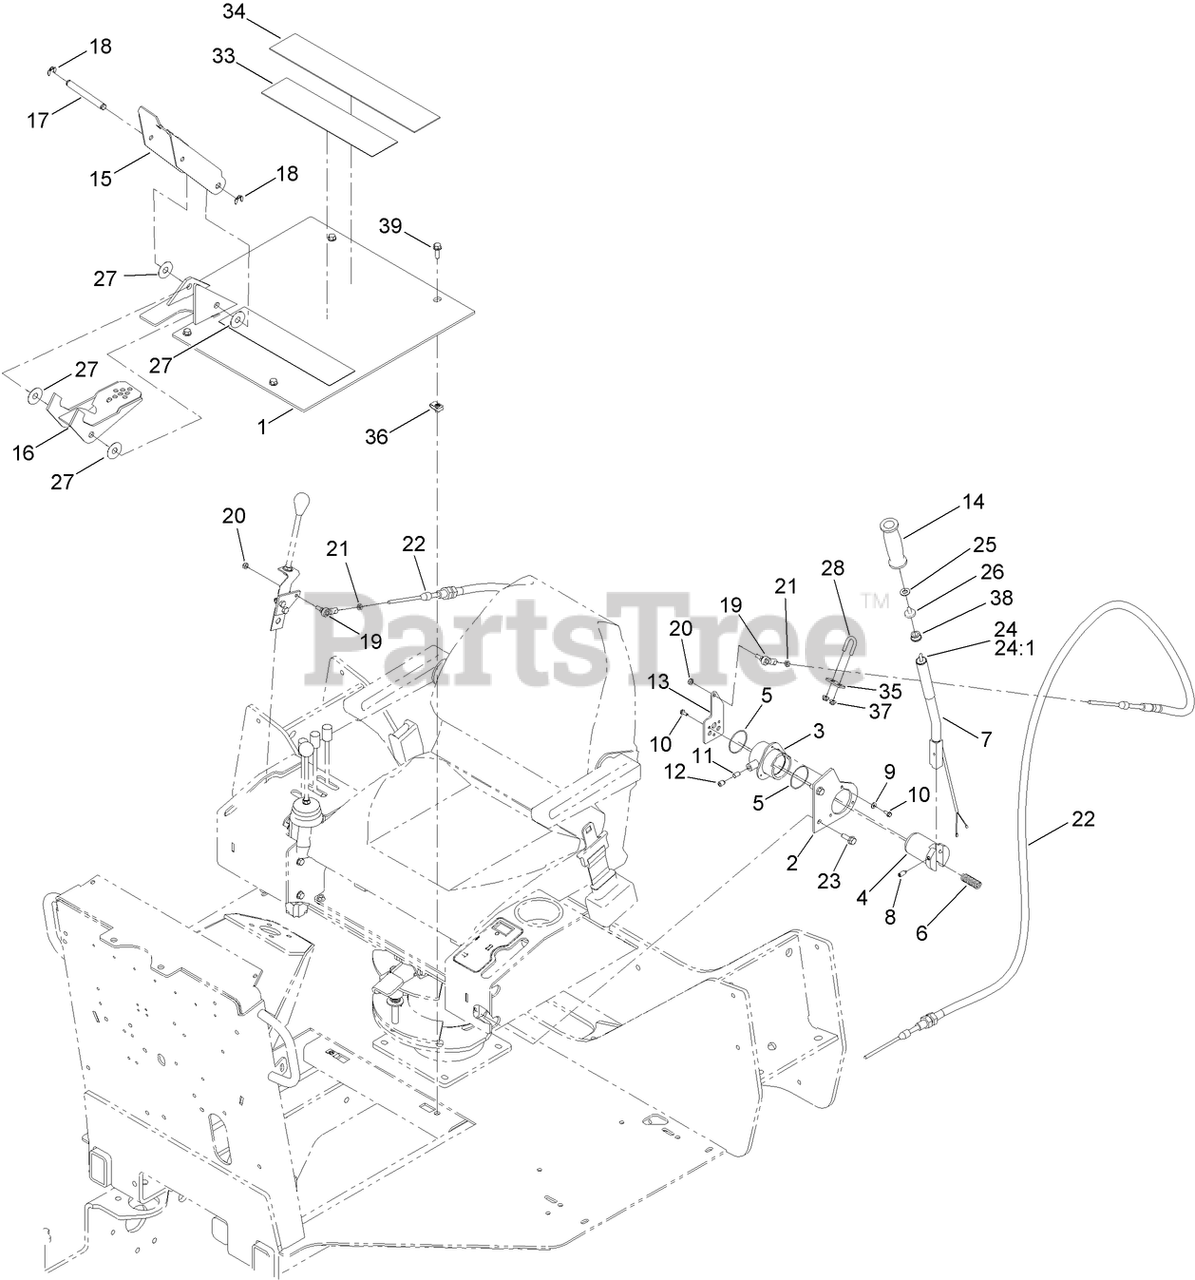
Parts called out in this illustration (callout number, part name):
1	PLATE-FLOOR
2	PLATE-GUSSET
5	O-RING
6	SPRING-Locking
7	HANDLE
8	SCREW-Set
9	WASHER-FLAT
10	SCREW-HWH
11	PLUG-FRICTION
12	SCREW-HSH
13	PLATE-CONTROL
14	GRIP-Handle
15	PEDAL-TOE
16	PEDAL-HEEL
17	PIN-Pedal
18	RING-CLIP, LOCKING
19	ROD END-FEMALE
20	NUT-LOCK, NI
21	NUT-JAM
22	GROUND DRIVE CONTROL CABLE ASM
23	SCREW-HHF
24	ON/OFF TOGGLE SWITCH ASM
24:1	SWITCH-TOGGLE
25	WASHER-FLAT
26	BOOT-SWITCH, TOGGLE
27	WASHER
33	STRIP-ANTI SKID
34	STRIP-ANTI SKID
36	NUT-CLIP, U
37	NUT-HF
38	BUSHING
39	SCREW-HHF
